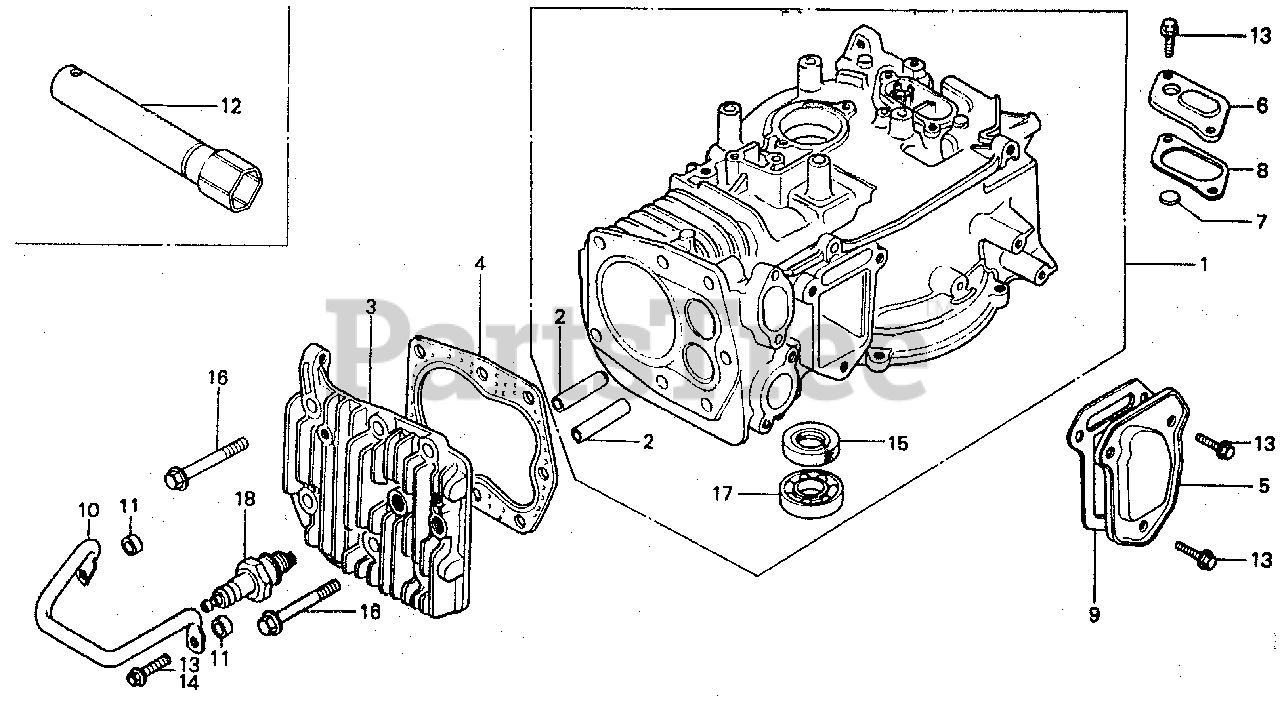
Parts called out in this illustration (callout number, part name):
1	CYLINDER ASSY.
2	GUIDE, VALVE (OS)
3	CYLINDER HEAD
4	GASKET, CYLINDER HEAD
5	COVER, TAPPET
6	CAP, BREATHER CHAMBER
7	VALVE, BREATHER
8	GASKET, BREATHER CAP
9	GASKET, TAPPET COVER
10	GUARD, PLUG
12	WRENCH, SPARK PLUG
13	BOLT, FLANGE (6X12) (CT200)
15	OIL SEAL (25X41X6)
16	BOLT, FLANGE (8X45)
17	BEARING, RADIAL BALL (6205)
18	SPARK PLUG (BPM6A-10) (NGK)
18	SPARK PLUG (W20MP-U10) (DENSO)
